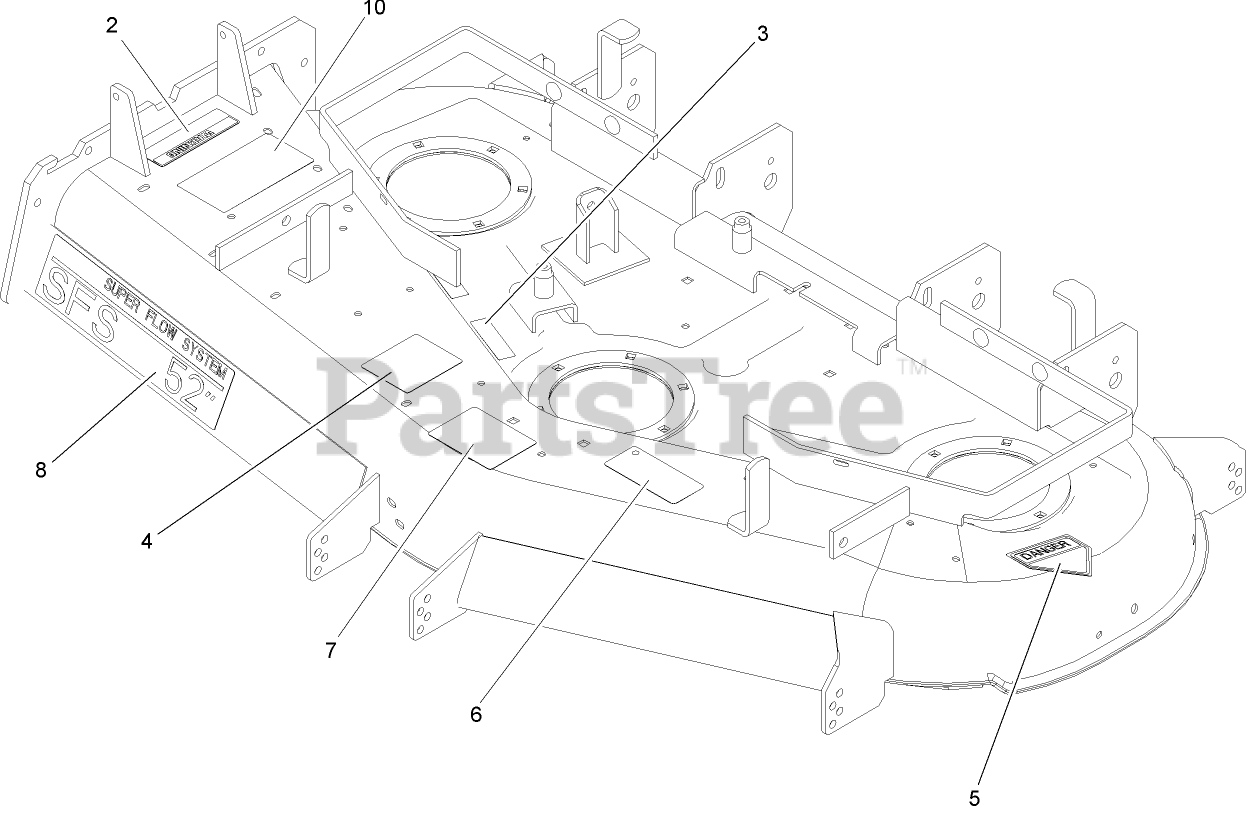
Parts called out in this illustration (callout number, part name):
2	DECAL-WARNING
3	DECAL-COVER, MISSING
4	DECAL-ROUTING, BELT
5	DECAL-DANGER
6	DECAL-TORQUE, BLADE BOLT
7	DECAL-WHEEL, GAGE
8	DECAL
10	DECAL-DANGER, THROWN OBJECT
